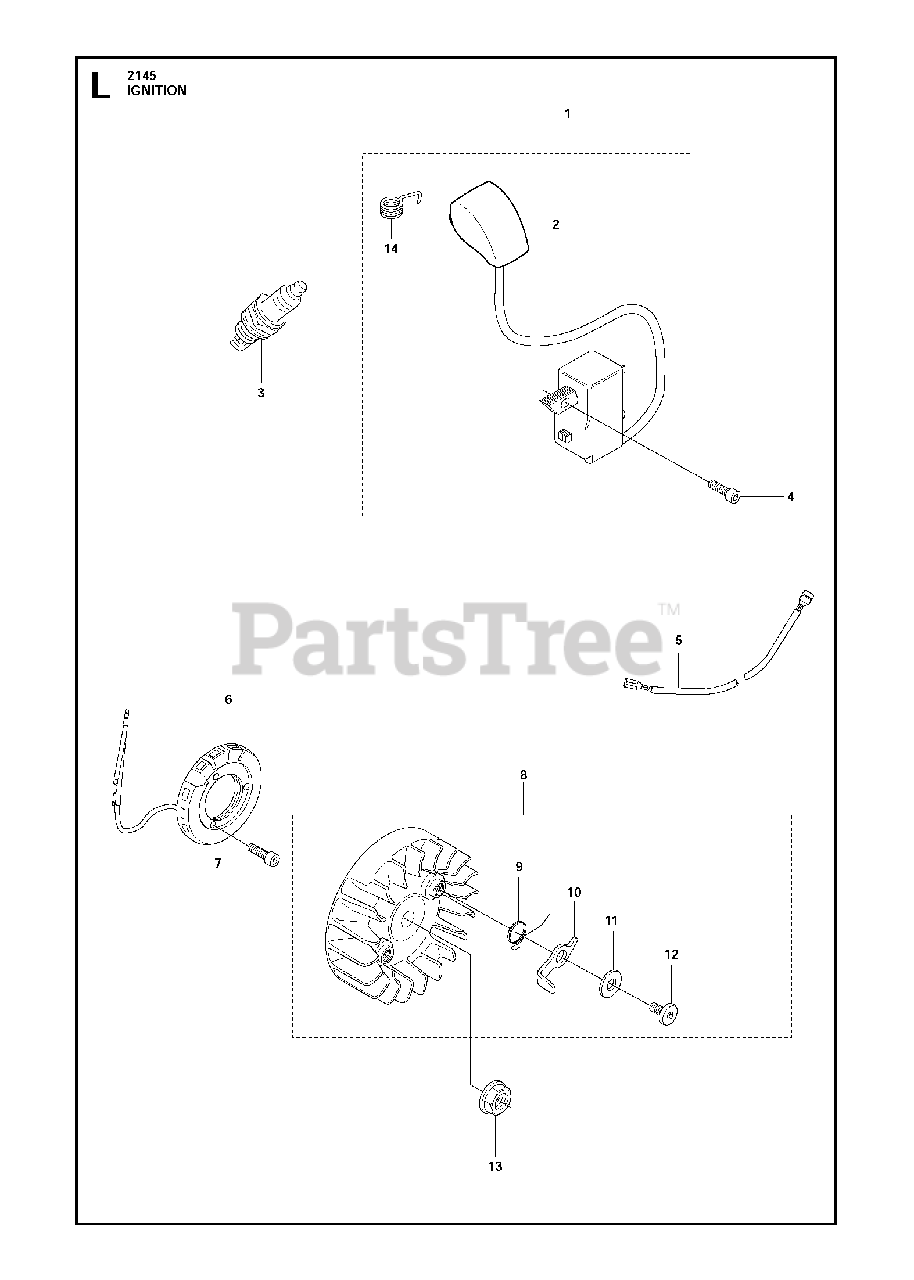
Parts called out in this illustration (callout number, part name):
1	IGNITION MODULE
2	SPARK PLUG CONNECTOR
3	SPARK PLUG RCJ6Y NLA
5	SHORTING LEAD
6	GENERATOR
7	SCREW
8	FLYWHEEL
9	SPRING
10	STARTER PAWL
11	WASHER
12	PIN, STARTER CATCH
13	NUT W/ WASHER
14	SPRING
